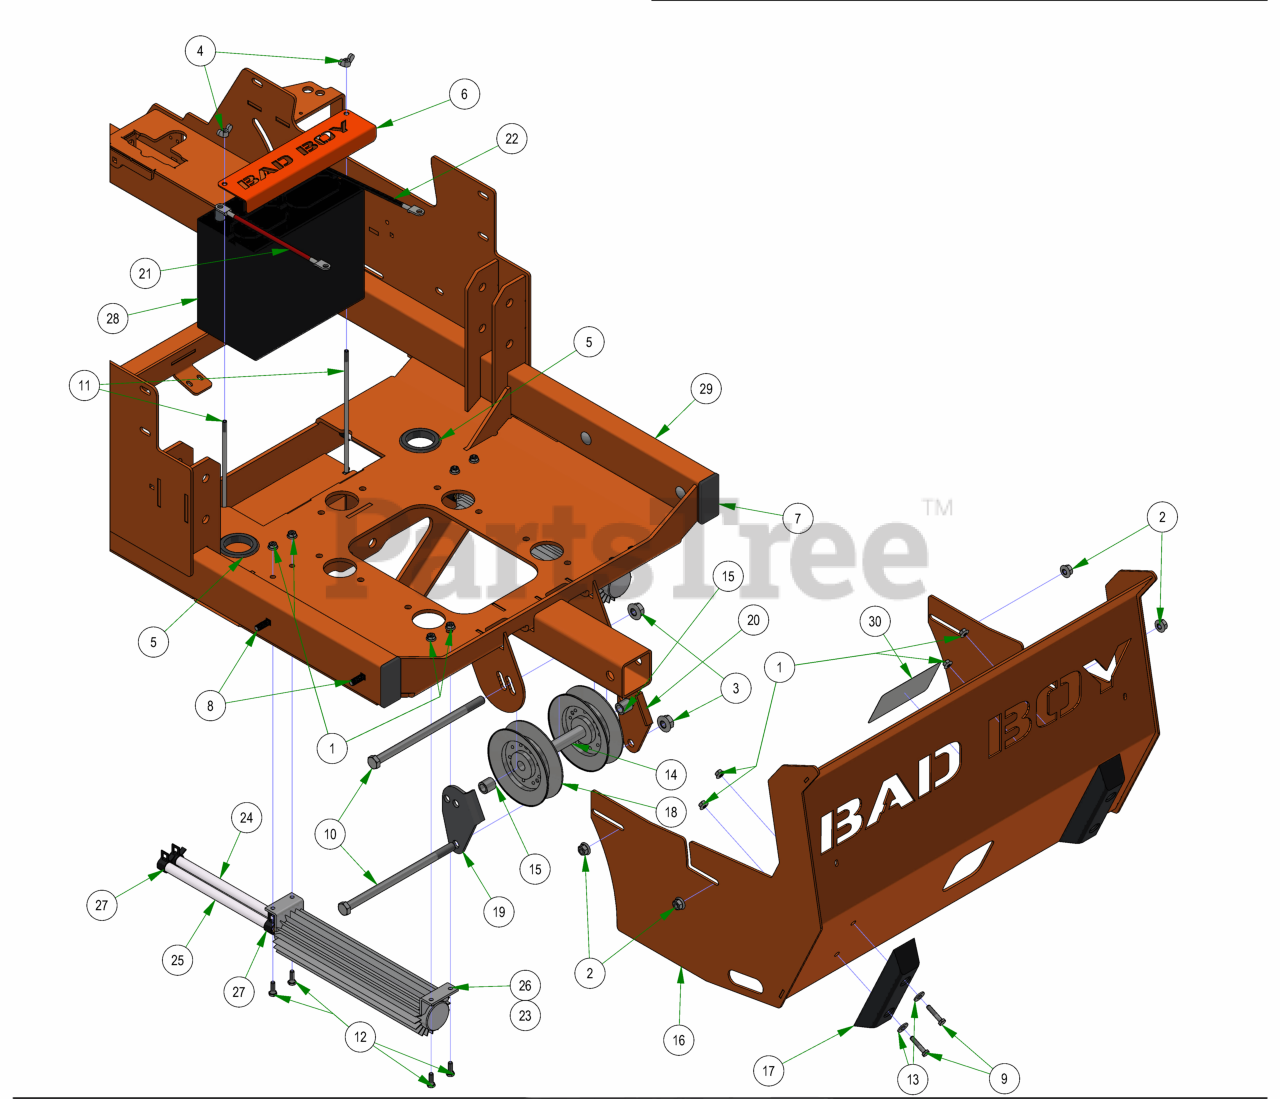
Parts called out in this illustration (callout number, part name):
1	1/4-20 NYL INSERT FLANGE LOCKNUT ZINC
2	3/8-16 NYLON INSERT FLANGE LOCKNUT (GR.F) ZINC
3	1/2-13 NYLON INSERT FLANGE LOCKNUT ZINC
4	1/4-20 WING NUT FORGED (TYPE A) LIGHT SERIES ZINC
5	2019 2" x .25 Rubber Grommet
6	2019 Horizontal Battery Hold Down Cover
7	1 1/2 x 3 Frame Plug
8	3/8" x 2 1/2" Carriage Bolt
9	1/4-20 X 1-1/4 HEX CAP SCREW (GR.5) ZINC
10	1/2-13 X 9 HEX CAP SCREW (GR.5) ZINC
11	1/4-20 X 9 CARRIAGE BOLT ZINC
12	1/4-20 X 3/4 HEX CAP SCREW (GR.5) ZINC
13	1/4 USS FLAT WASHER (3/4 OD) ZINC
14	2019 Pulley Spacer .75 x .5 x 4.375
15	.51 ID X .75 OD X .75 LGTH SOLID SPACER ZINC
16	2019 Horizontal Suspension Rear Cover
17	8" Rubber Bumper
18	2019 Outlaw Horizontal Rear V Pulley
19	Renegade Deck Belt Rear Keeper - Left
20	Renegade Deck Belt Rear Keeper-Right
21	Red Battery Cable - Diesel
22	Black Battery Cable - Diesel
23	Renegade Oil Cooler Assembly
24	3/8" Clear Hose - 14"
25	3/8" Clear Hose - 24"
26	2019 12" Oil Cooler With Fittings
27	3/8" Hose Clamp
28	Battery - Diesel/Renegade Models PF-516
29	2022 Horizontal Diesel Frame
30	2019 Renegade Pump Belt Route Decal
